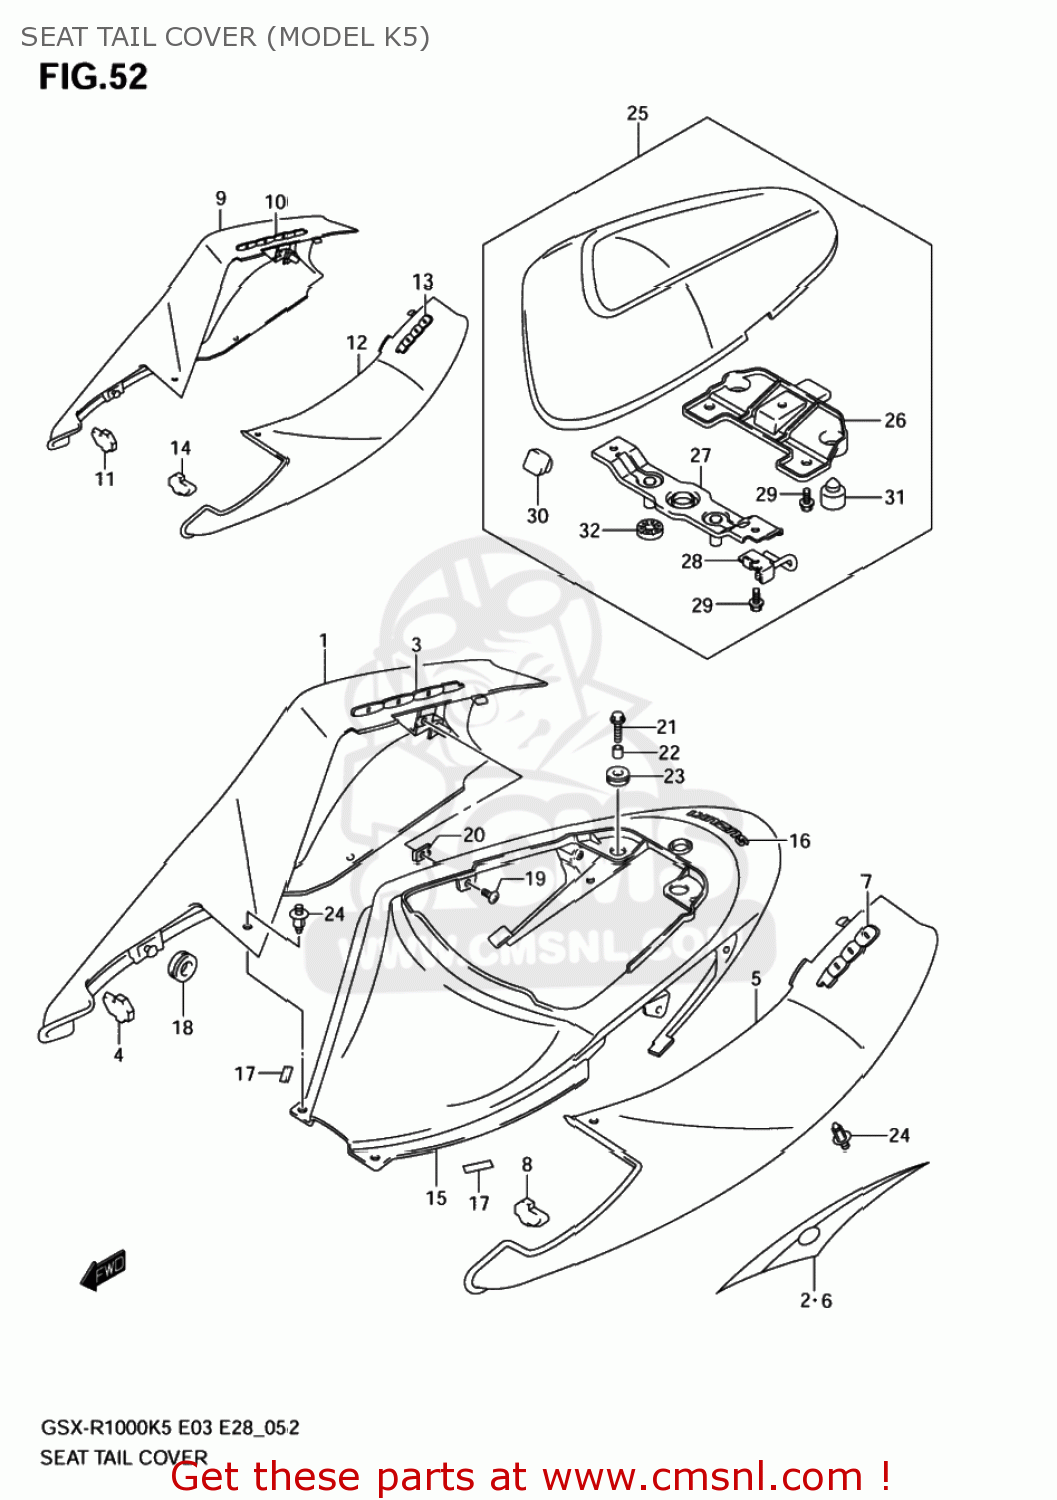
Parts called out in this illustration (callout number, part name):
1	COVER,SEAT TAIL
2	TAPE,SEAT TAIL COVER,R
3	EMBLEM,1000
4	CUSHION,SEAT TAIL COVER,R
5	COVER,SEAT TAI
6	TAPE,SEAT TAIL COVER,L
7	EMBLEM,1000
8	CUSHION,SEAT TAIL COVER,L
9	COVER,SEAT TAIL
10	EMBLEM,1000
11	CUSHION,SEAT TAIL COVER,R
12	COVER,SEAT TAI
13	EMBLEM,1000
14	CUSHION,SEAT TAIL COVER,L
15	COVER,SEAT TAIL CTR
16	EMBLEM,SUZUKI
17	TAPE(6X25X0.13)
18	CUSHION
19	SCREW
20	NUT
21	BOLT(6X20)
22	SPACER(6.5X10X9.4)
23	CUSHION
24	CLIP(BLACK)
25	BOX,SEAT TAIL
26	BOTTOM,SEAT TAIL BOX
27	STRIKER
28	HOLDER,HELMET
29	BOLT
30	CUSHION
31	CUSHION
32	CUSHION
